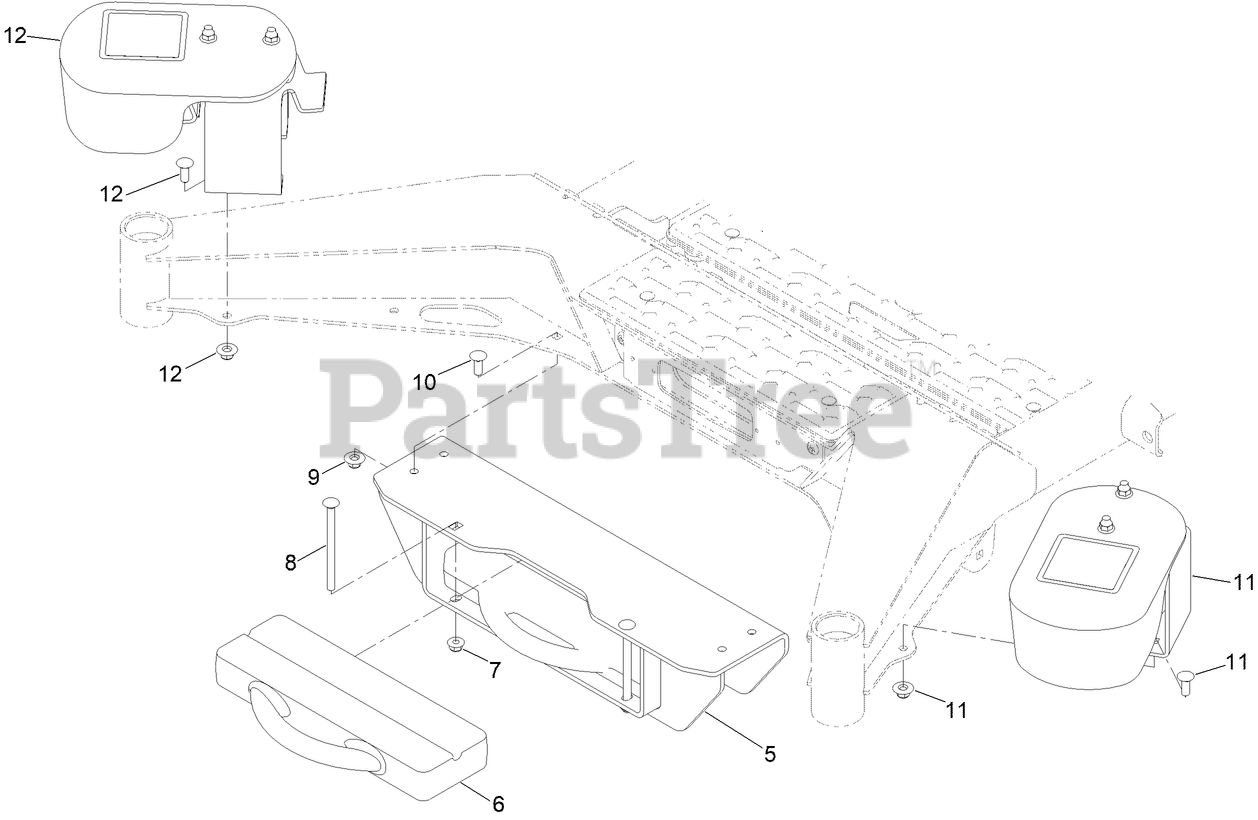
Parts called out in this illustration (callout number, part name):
5	WEIGHT BRACKET ASM
7	NUT-HF, NI
8	BOLT-CARR
9	NUT-FLANGE, NI
10	SCREW-CARR
11	ASM-LH CASTER WEIGHT
12	ASM-RH CASTER WEIGHT
